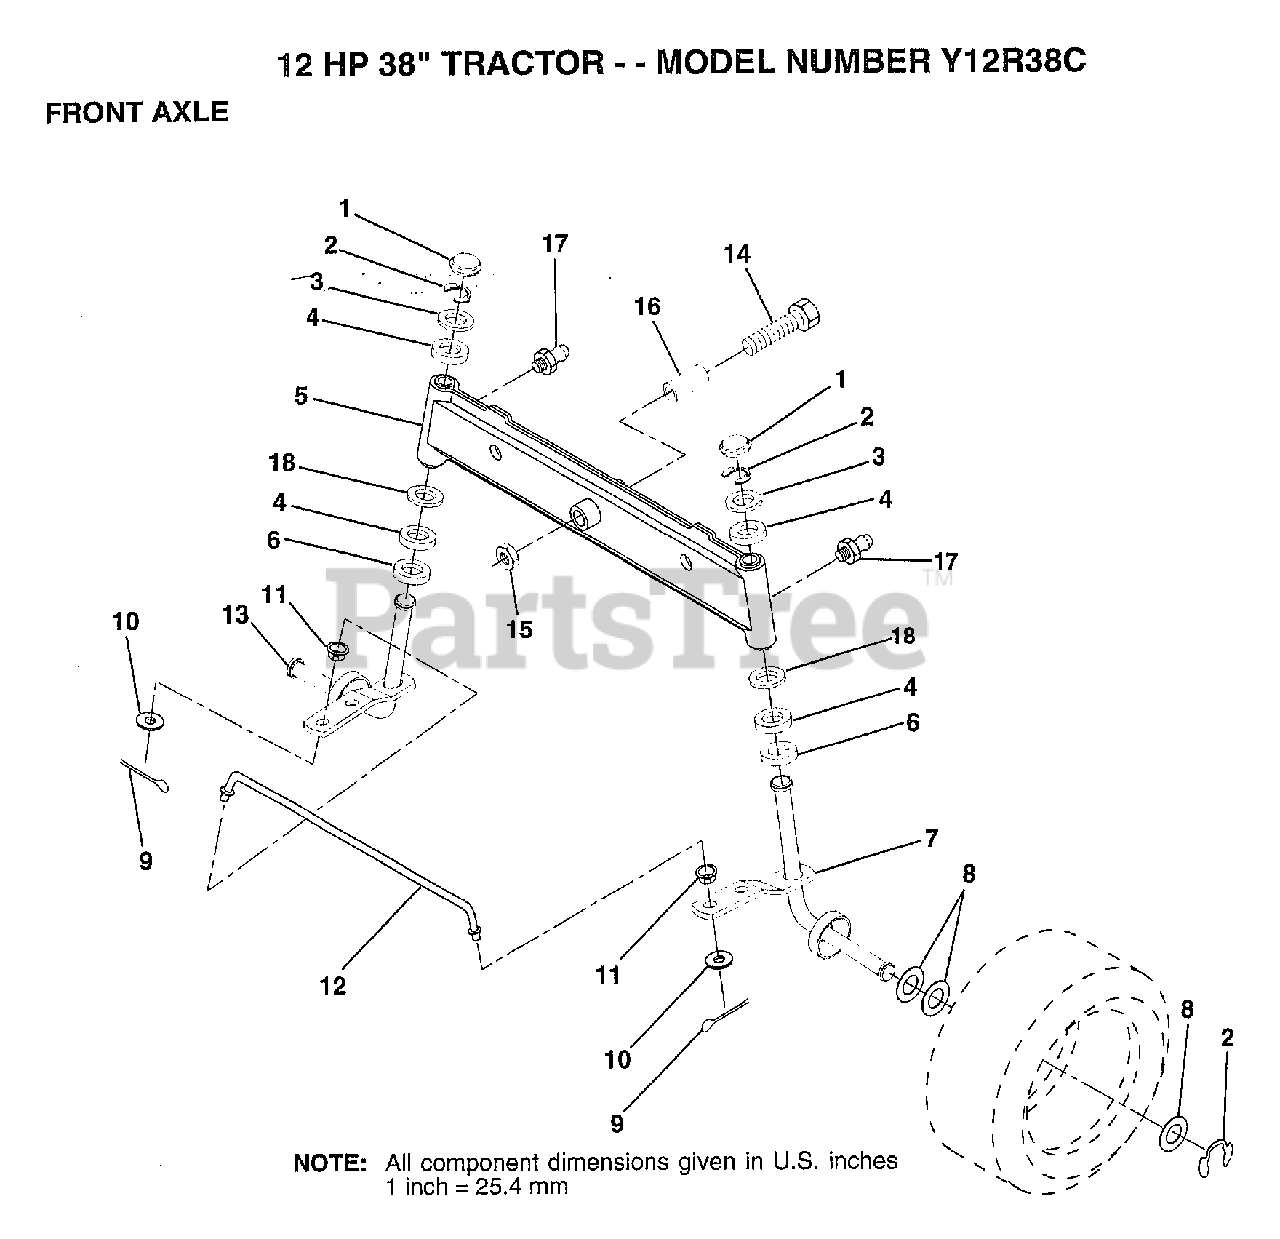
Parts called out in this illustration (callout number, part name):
1	CAP
2	RING
3	WASHER
4	COL. SRTG. BEAR.
5	AXLE ASM FRONT
6	WASHER .T
7	SPINDLE ASM RH
8	WASHER
9	COTTER PIN
10	WASHER
11	BUSHING.DRAGLINK
12	TIE ROD
13	SPINDLE ASM LH
14	BOLT HEX 5/8-11
15	"NUT-LOC,FLANGE LT"
16	BEARING
17	ZERK M
18	WASHER
